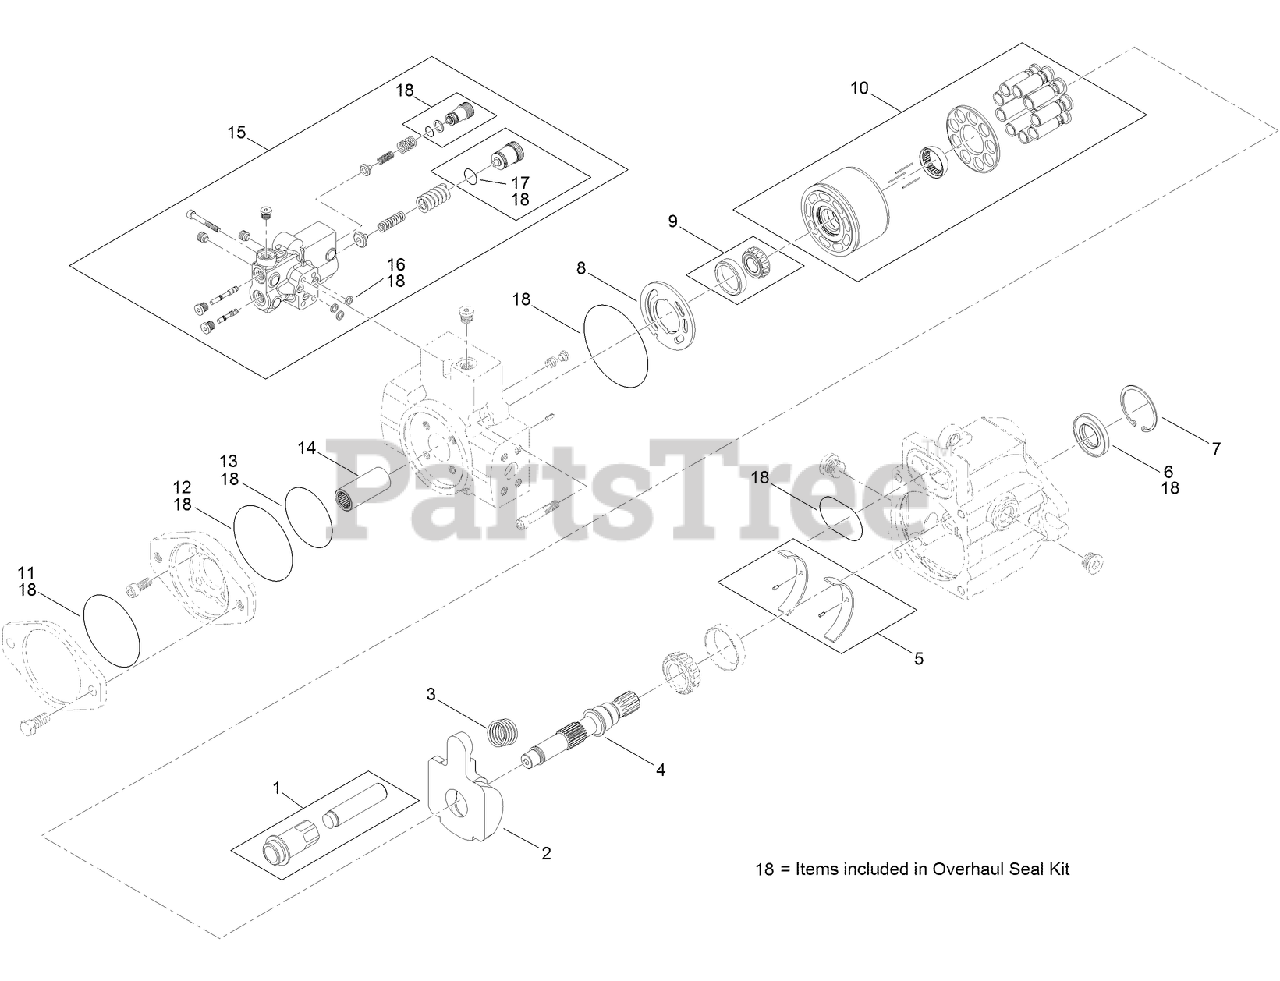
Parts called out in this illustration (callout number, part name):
1	SERVO PISTON KIT
2	SWASHPLATE
3	SPRING-BIAS
5	SWASH PLATE KIT
6	LIP SEAL
8	PLATE-VALVE
9	REAR BEARING KIT
10	CYLINDER BLOCK KIT
11	O-RING
12	O-RING
13	O-RING
14	COUPLING
15	CONTROL KIT
16	RING-SEAL
17	O-RING
18	OVERHAUL SEAL KIT
